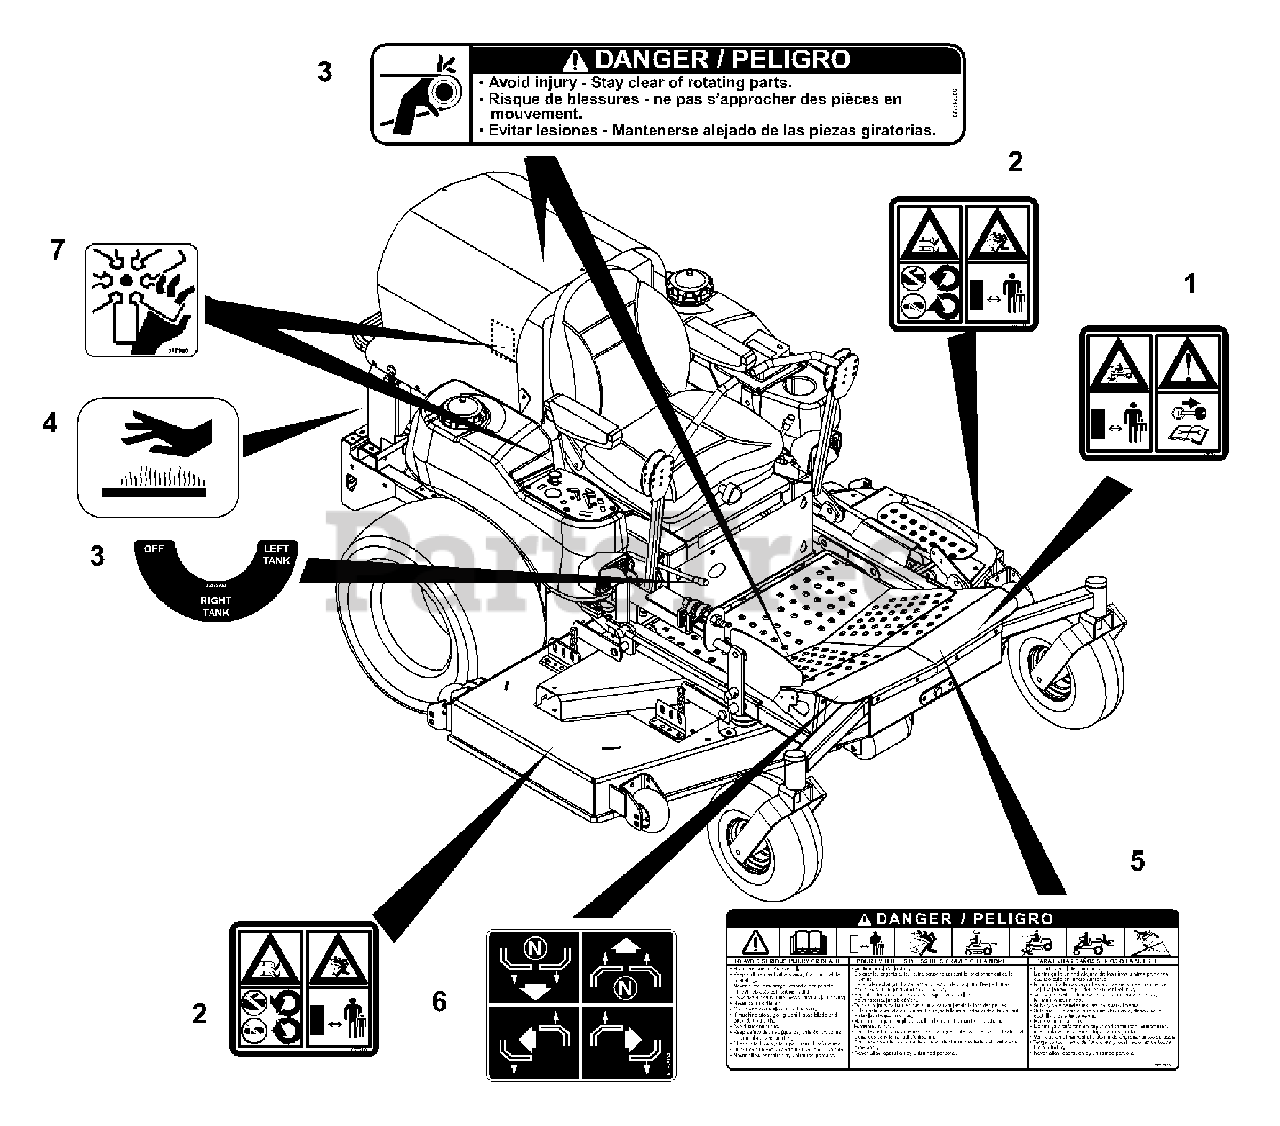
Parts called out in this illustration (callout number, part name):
1	DECAL, CE CAUTION
2	DECAL, CE DECK
3	SET, DECAL-COMMON DANGER/FUEL
4	DECAL, HOT SURFACE
5	DECAL, WARNING
6	DECAL, INSTRUCTIONAL-STEERING
7	DECAL, DANGER FAN
